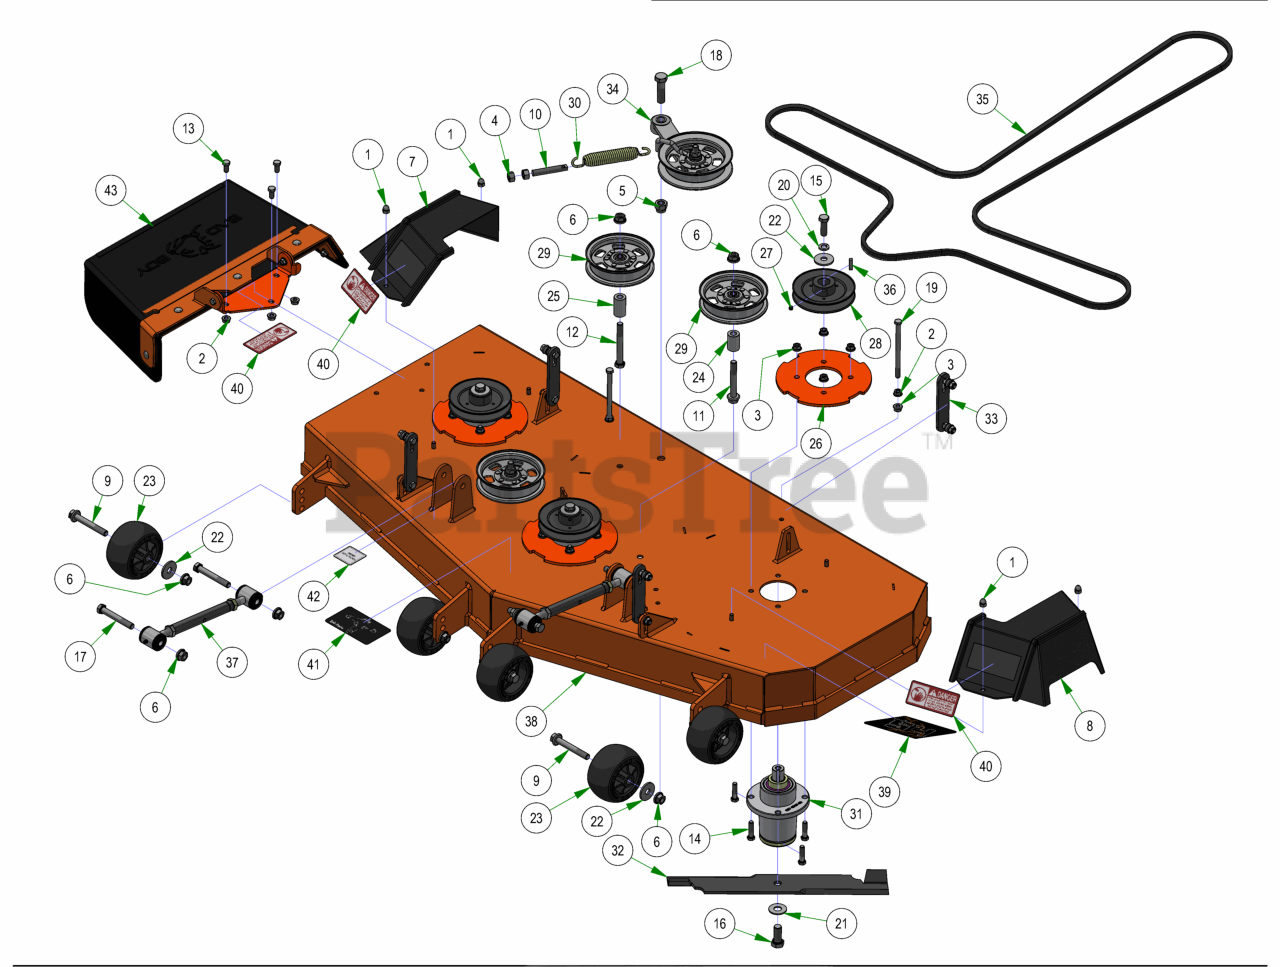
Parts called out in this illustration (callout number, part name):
1	5/16-18 ACORN NUT HIGH-CROWN ZC
2	3/8-16 HEX SERRATED FLANGE NUT HARD/ZINC
3	3/8-16 NYLON INSERT FLANGE LOCKNUT (GR.F) ZINC
4	1/2-13 HEX NUT ZINC
5	5/8-11 NYLON INSERT LOCKNUT ZINC
6	1/2-13 NYLON INSERT FLANGE LOCKNUT ZINC
7	2021 Maverick 54”/60” RH Pulley Cover
8	2021 Maverick 54”/60” LH Pulley Cover
9	1/2-13 X 90MM HEX FLANGE BOLT W/SHOULDER (GR.8) ZINC
10	All Thread
11	1/2-13 X 3-1/2 HEX FLANGE BOLT (GR.8) ZINC
12	1/2-13 X 4 HEX CAP SCREW (GR.8) ZINC YELLOW
13	3/8-16 X 3/4 HEX CAP SCREW (GR.5) ZINC
14	3/8-16 X 1-1/2 HEX CAP SCREW (GR.5) ZINC
15	1/2-20 X 1-1/2 HEX CAP SCREW (GR.5) ZINC
16	5/8-18 X 1-1/2 HEX CAP SCREW (GR.8) ZINC YELLOW
17	1/2-13 X 3-1/2 HEX CAP SCREW (GR.5) ZINC
18	5/8-11 X 2-1/4 HEX CAP SCREW (GR.5) ZINC
19	3/8-16 X 5-1/2 HEX CAP SCREW (GR.5) ZINC
20	1/2 SPLIT LOCKWASHER (GR.8) ZINC/YELLOW
21	5/8 USS FLAT WASHER (1-3/4" OD) GR.8 ZINC YELLOW
22	1/2 BELLEVILLE WASHER (1-5/8 OD X .140 THK) ZINC
23	Deck Wheel
24	.502 ID X .750 OD X 1.500 Long Spacer
25	1 3/4" Pulley Spacer
26	Deck Spindle Support Plate
27	5/16-24 X 1/4 SOCKET SET SCREW (CUP PT) PLAIN
28	5.25" Deck Spindle Pulley
29	5-3/4 Idler Pulley
30	Deck Idler Spring
31	Spindle Assembly
32	54" Fusion Blade for Avenger/ZT/Mav/Outlaw/Revolt
33	Deck Hanger Assembly
34	Maverick HD & Down Deck Idler Assembly
35	B155.75 Deck Belt
36	1/4 X 1 SQ MACHINERY KEY 1018 STL PLN
37	2018 Maverick Turnbuckle (Top Link)
38	2025 54" x 5" Deck
39	54" Grip Deck Decal
40	Danger Decal-Spindle/Discharge
41	Deck Belt Route Decal
42	Deck Impact Patent Decal 9591803
43	Discharge Chute Assembly
